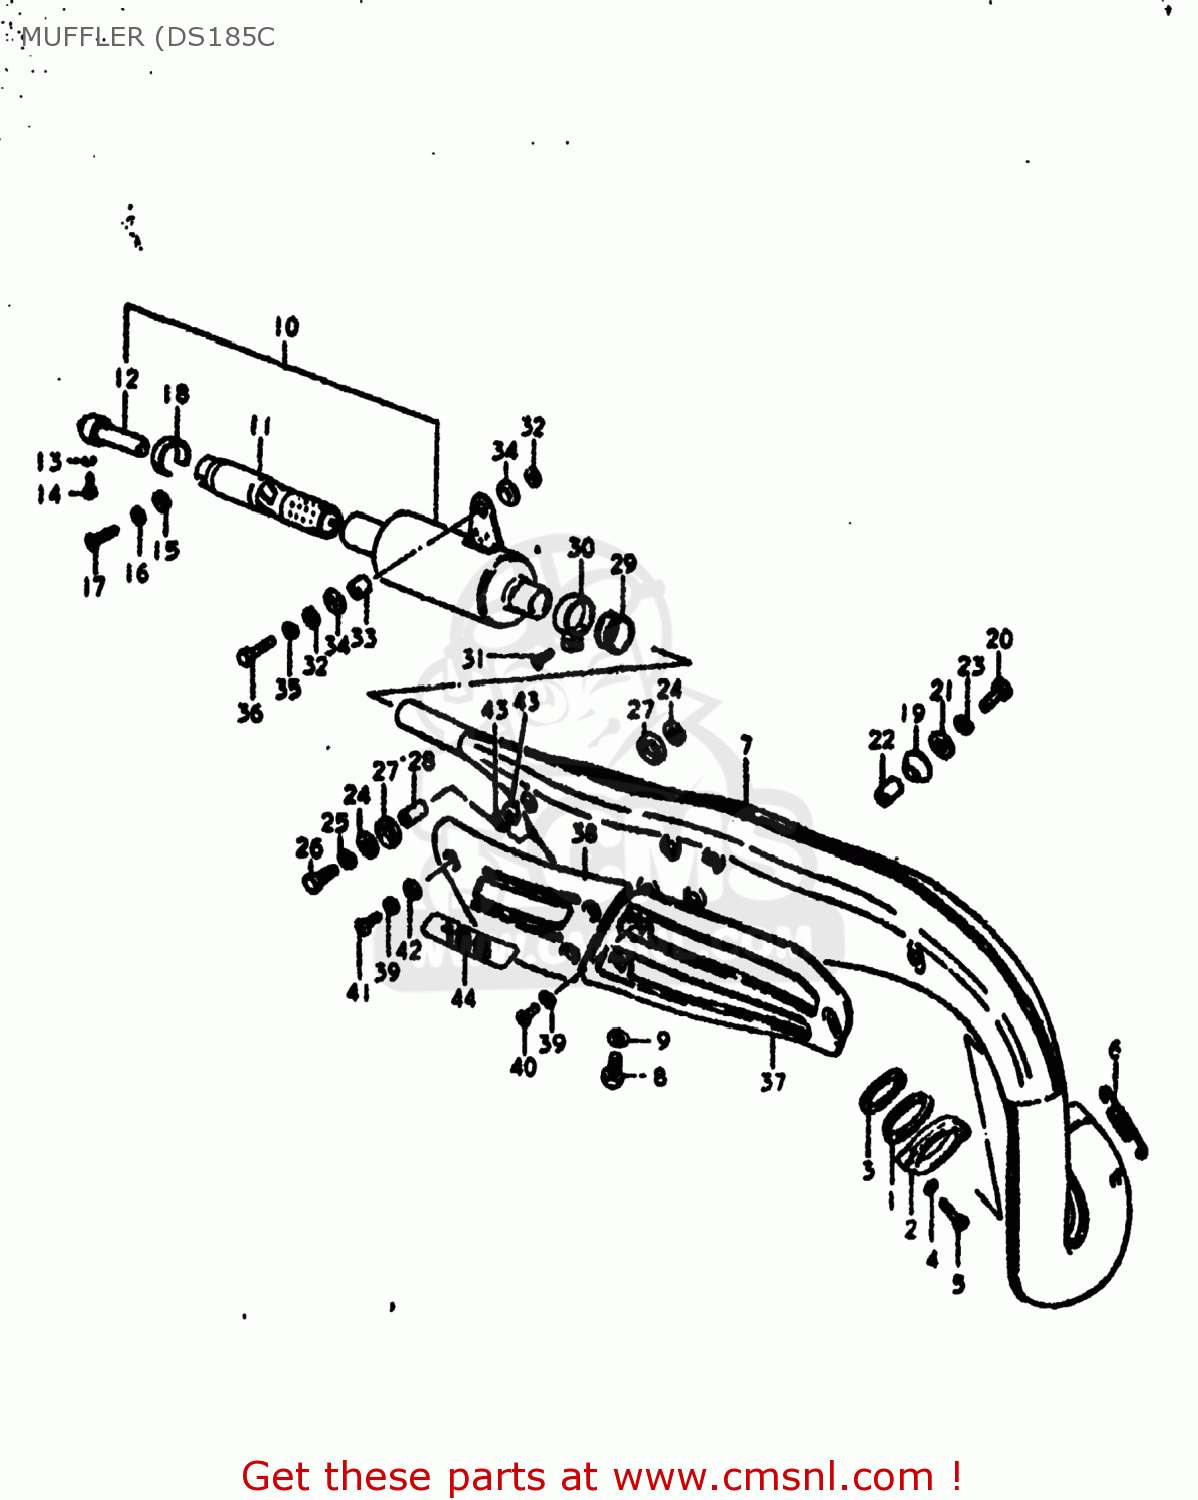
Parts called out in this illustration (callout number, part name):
1	GASKET,EXHAUST PIPE (NAS)
2	CLAMP,EXHAUST PIPE
3	CUSHION,EXHAUST PIPE
4	LOCK WASHER
5	BOLT
6	SPRING
7	BODY,MUFFLER
8	BOLT 10X9
9	GASKET(10X14X3.6) (NAS)
10	MUFFLER ASSEMBLY
11	ARRESTER,SPARK
12	TUBE,MUFFLER CLEAN OUT
13	LOCK WASHER
14	SCREW
15	WASHER
16	LOCK WASHER
17	SCREW(6X8)
18	BAND,SPARK ARRESTER
19	DAMPER,MUFFLER,FR
20	BOLT
21	WASHER
22	SPACER (8X12X15)
23	LOCK WASHER
24	WASHER (8.2X20X1.6)
25	LOCK WASHER
26	BOLT
27	CUSHION
28	SPACER (8.6X13.8X9.8)
29	CONNECTOR,MUFFLER
30	CLAMP
31	SCREW
32	WASHER
33	SPACER (8.6X13.8X9)
34	CUSHION
35	LOCK WASHER
36	BOLT
37	COVER,MUFFLER,FRONT
38	COVER,MUFFLER
39	LOCK WASHER
40	SCREW
41	SCREW 6X12
42	WASHER
43	GASKET 6.2X12X1.5 (MCA)
44	EMBLEM,MUFFLER COVER
